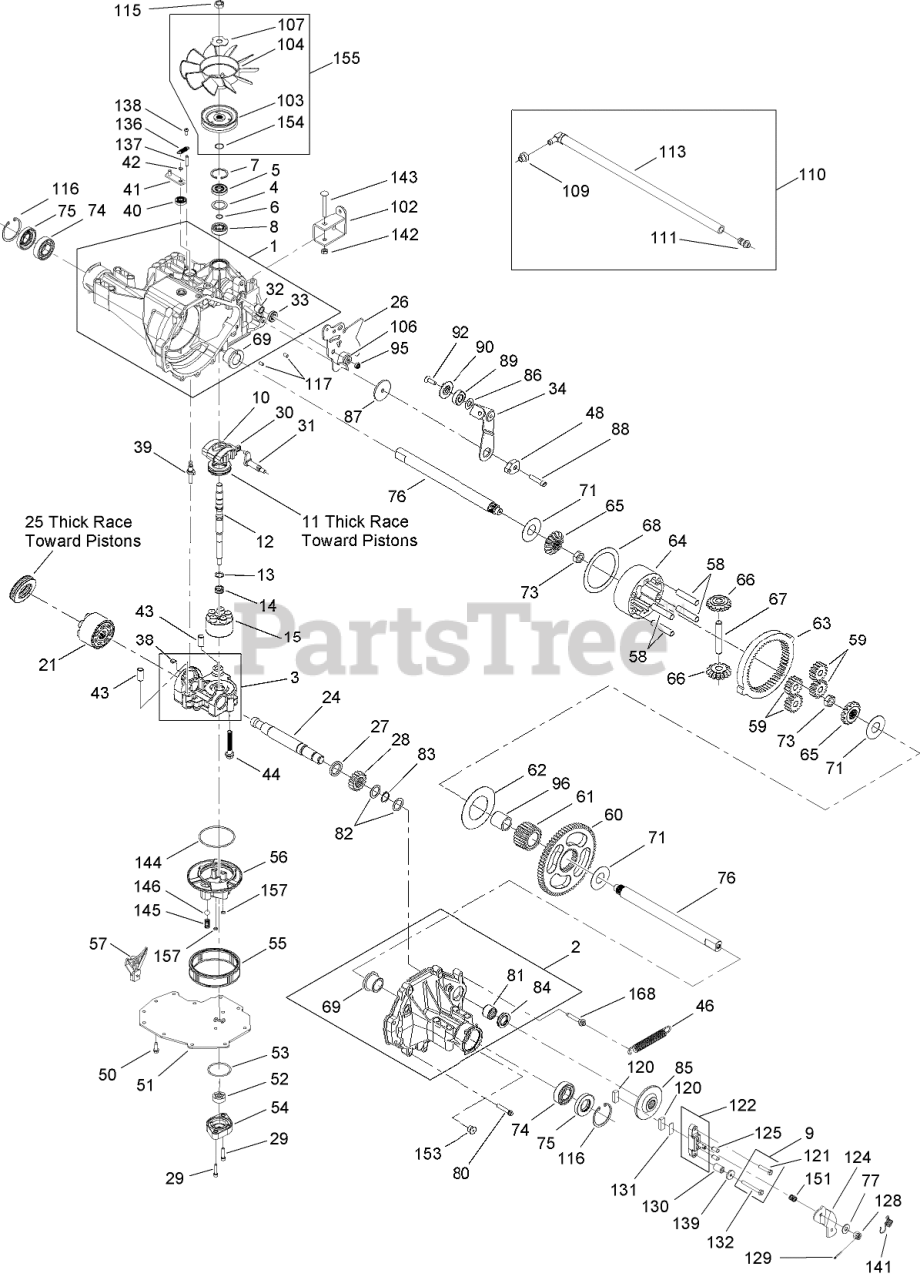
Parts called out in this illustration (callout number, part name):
1	MAIN HOUSING ASM
2	RIGHT HAND HOUSING ASM
3	CENTER SECTION ASM
4	SPACER
5	SEAL-LIP
6	RING-WIRE, RETAINING
7	RING-RETAINING
8	BEARING-SHAFT, BALL
9	BRAKE BOLT KIT
10	SWASHPLATE-VARIABLE
11	BEARING-THRUST
12	SHAFT-INPUT
13	WASHER-THRUST
14	SPRING-BLOCK
15	CYLINDER BLOCK KIT
21	CYLINDER BLOCK ASM
24	SHAFT-OUTPUT
25	BEARING-THRUST
26	ARM-CONTROL
27	SPACER
28	GEAR-PINION, 16T
29	CAPSCREW
30	GUIDE-SLOT
31	TRUNNION ASM
32	BUSHING-TRUNNION
33	SEAL-LIP
34	ARM-RETURN
38	BYPASS PLATE KIT
39	ACTUATOR-BYPASS
40	SEAL-LIP
41	ARM-BYPASS
42	RING-RETAINING
46	SPRING-RETURN, 5 INCH (MEDIUM)
48	PUCK-ADJUSTING
51	COVER-LOWER
52	GEROTOR ASM
53	O-RING
54	COVER-GEROTOR
55	FILTER KIT
56	MANIFOLD-CHARGE
57	RETAINER-BEARING, MOTOR
58	PIN-CARRIER
59	GEAR-PLANET, 15T
60	GEAR-SPUR, 67T
61	GEAR-SUN, 21T
62	PLATE-THRUST, PLANET
63	GEAR-RING, 51T
64	CARRIER-PLANETARY
65	GEAR-MITER
66	GEAR-MITER
68	PLATE-THRUST
69	BEARING-FLANGE
71	WASHER
73	NUT-HJ
74	BEARING-BALL
76	SHAFT-AXLE
77	WASHER-PIVOT
80	SCREW-TTH
81	BEARING-NEEDLE
82	WASHER
83	RING-RETAINING
84	SEAL-LIP
85	DISK-BRAKE
86	WASHER
87	WASHER
89	BEARING
90	SPACER-LOCATING
92	SCREW-COUNTERSUNK
95	NUT-HEX, LOCK
96	BEARING-SLEEVE
